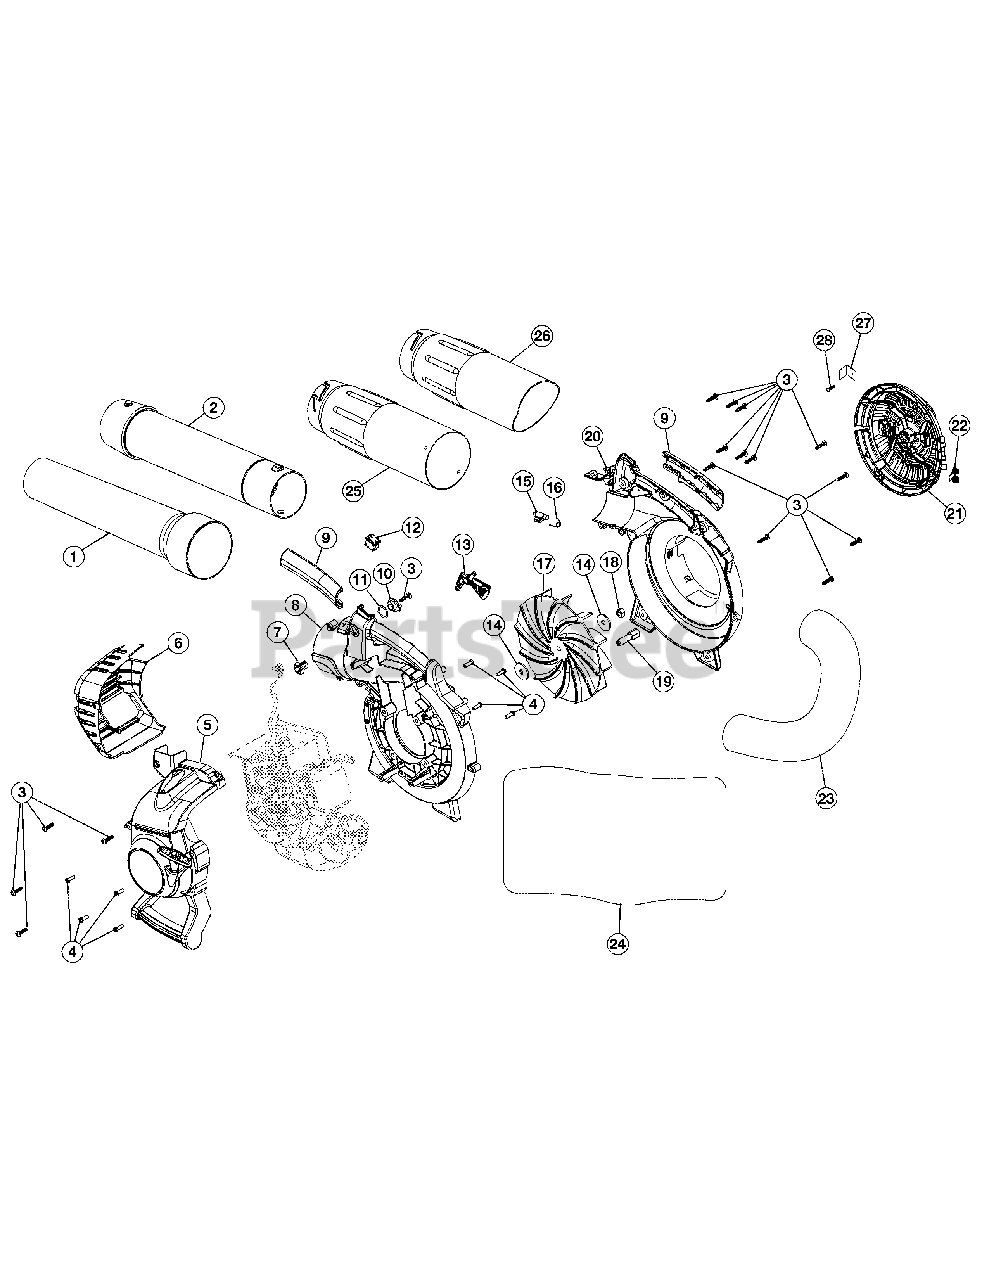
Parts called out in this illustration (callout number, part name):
1	Lower Tube
2	Upper Tube
4	Screw
5	Engine Cover Assembly (Incl. 3 & 4)
6	Muffler Cover Assembly (Incl. 3)
7	Outer Trigger Lock
8	Impeller Housing
9	Handle Grips
10	Inner Trigger Lock
11	Wavey Washer
13	Throttle Trigger
15	Latch Tube
16	Latch Spring
18	Nut
20	Impeller Housing
21	Intake Cover
25	Upper Vac Tube
26	Lower Vac Tube
28	Screw
